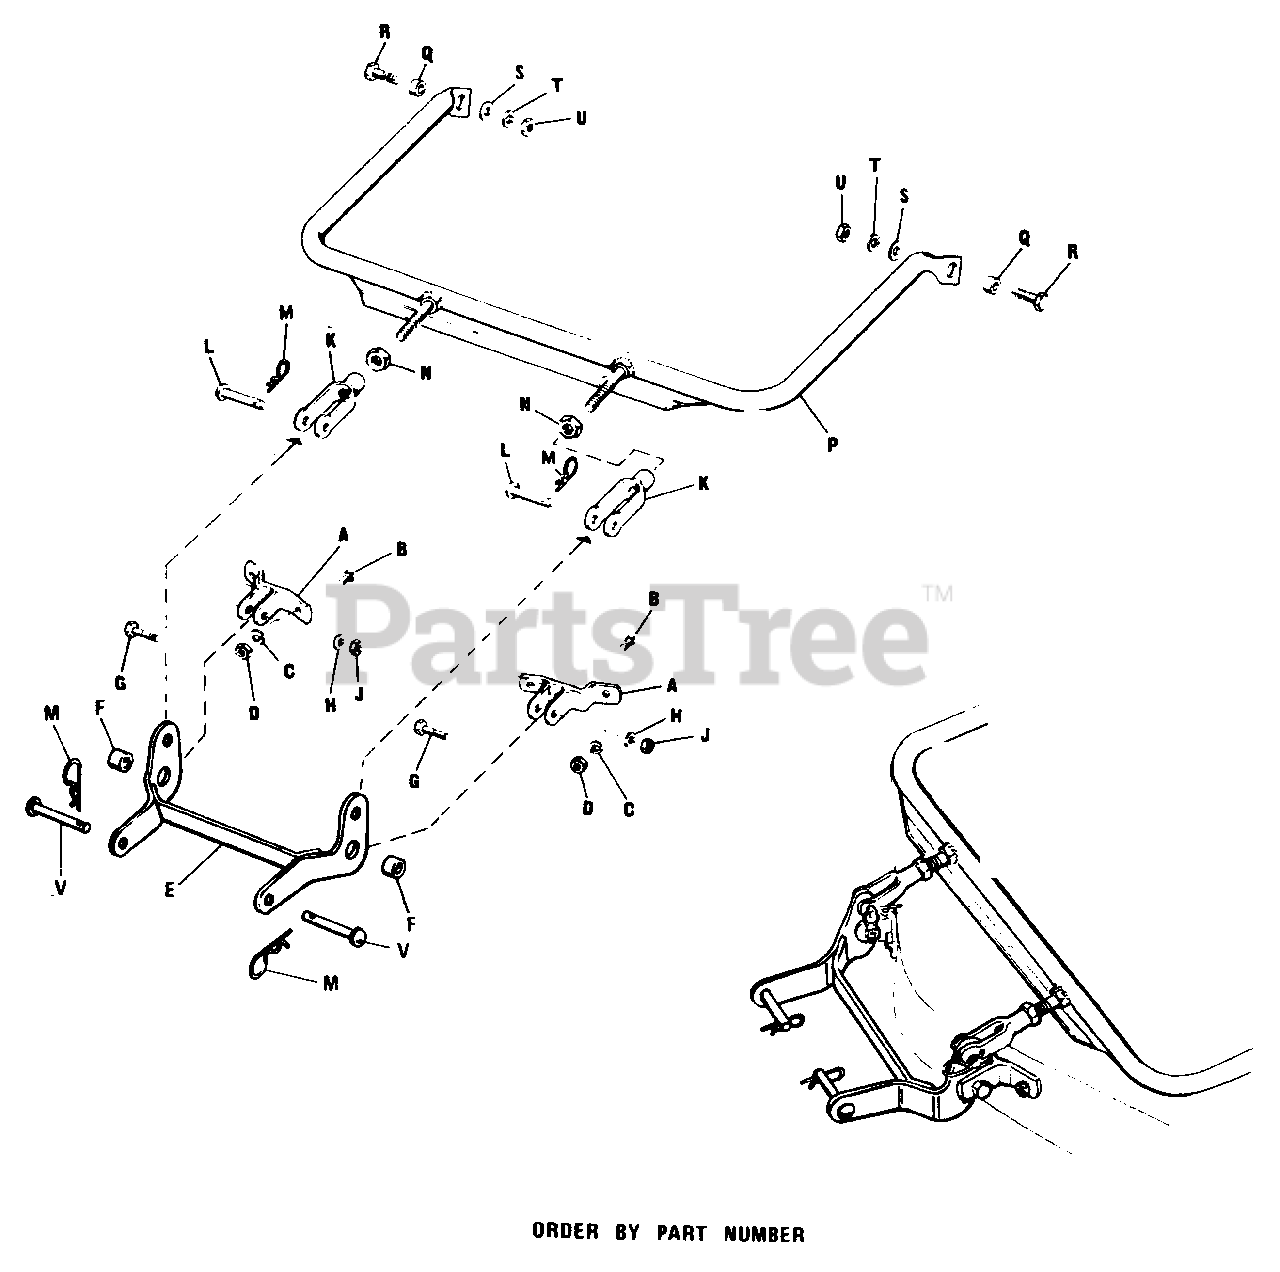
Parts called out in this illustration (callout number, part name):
A	Front Bracket Assembly
B	Carriage Bolt, 3/8"-16 x 1"
C	Lock Washer, 3/8"
D	Full Hex. Nut, 3/8"-16
E	Rocker Arm
G	Hex. Cap Screw, 1/2"-13 x 1-1/4 "
H	Lock Washer, 1/2"
J	Full Hex Nut, 1/2"-13
K	End Adj. Yoke
M	Spring Clip
N	Hex. Jam Nut, 1/2"-20
P	Bail Assembly
R	Hex. Cap Screw, 1/2"-13 x 1-1/4"
S	Plain Washer, 1/2"
T	Lock Washer, 1/2"
U	Full Hex Nut, 1/2"-13
V	Pin
